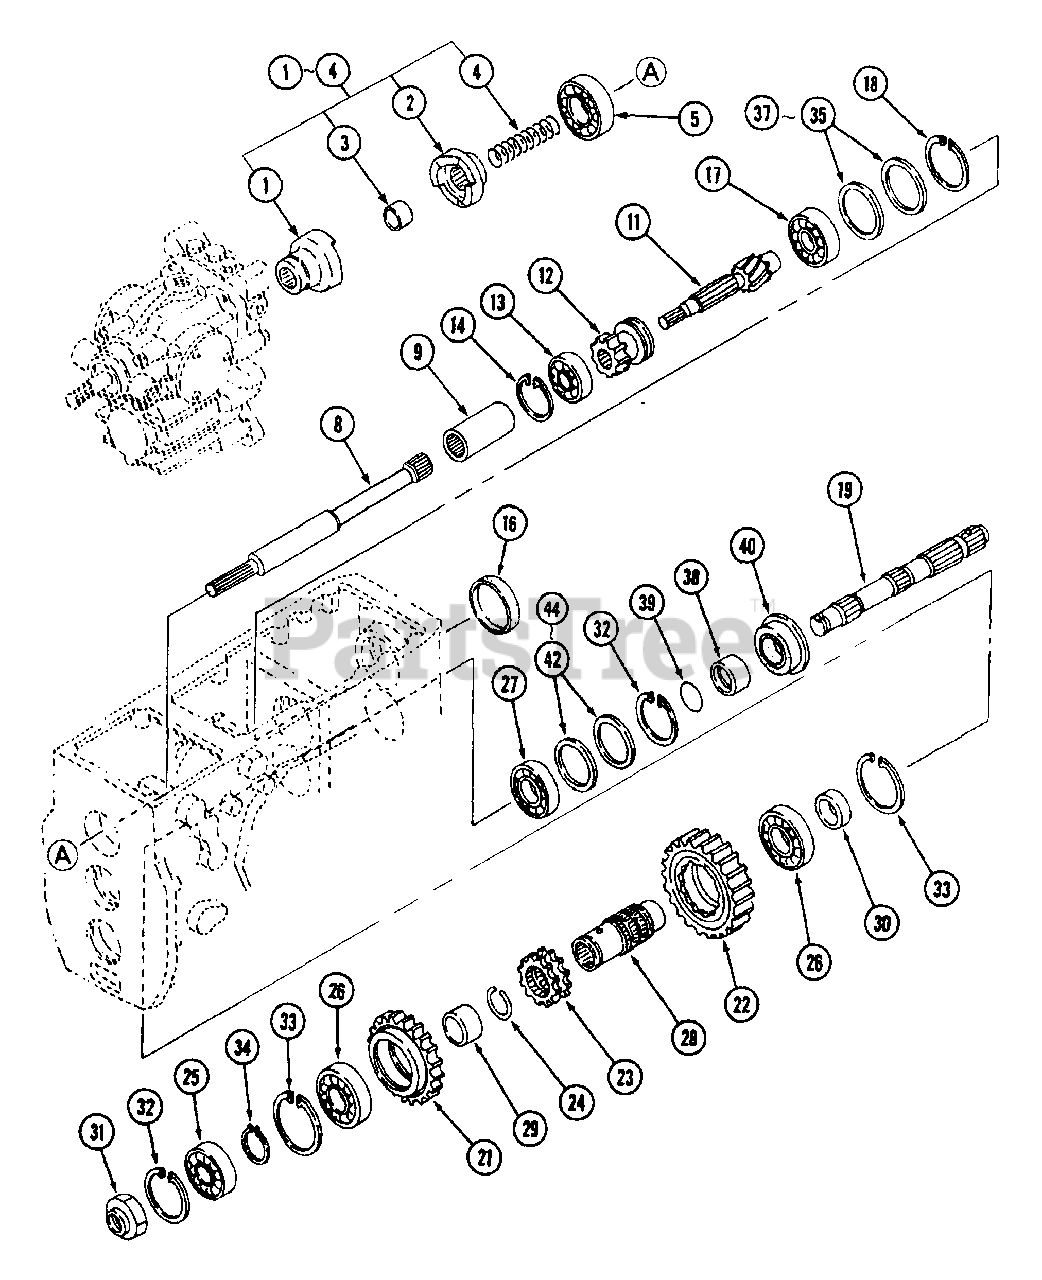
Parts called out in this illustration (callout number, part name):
9	Collar
11	Shaft, PTO Drive
34	Ring
40	Seal,Oil
